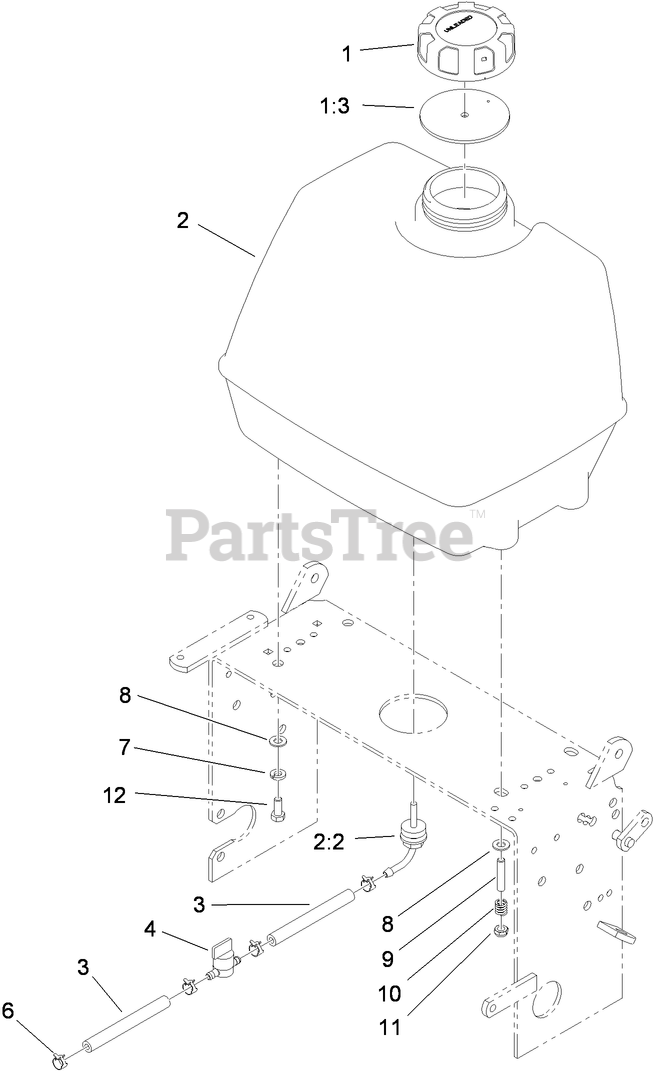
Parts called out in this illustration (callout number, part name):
1	GAS CAP ASM
1:3	GASKET-CAP, GAS
2	FUEL TANK ASM
2:2	FITTING-FUEL, BULKHEAD
3	HOSE-FUEL
4	VALVE-FUEL
6	CLAMP-HOSE
7	WASHER-LOCK
8	WASHER-PLAIN
10	SPRING-TANK, FUEL
11	NUT-LOCK, NI
12	SCREW-HH
